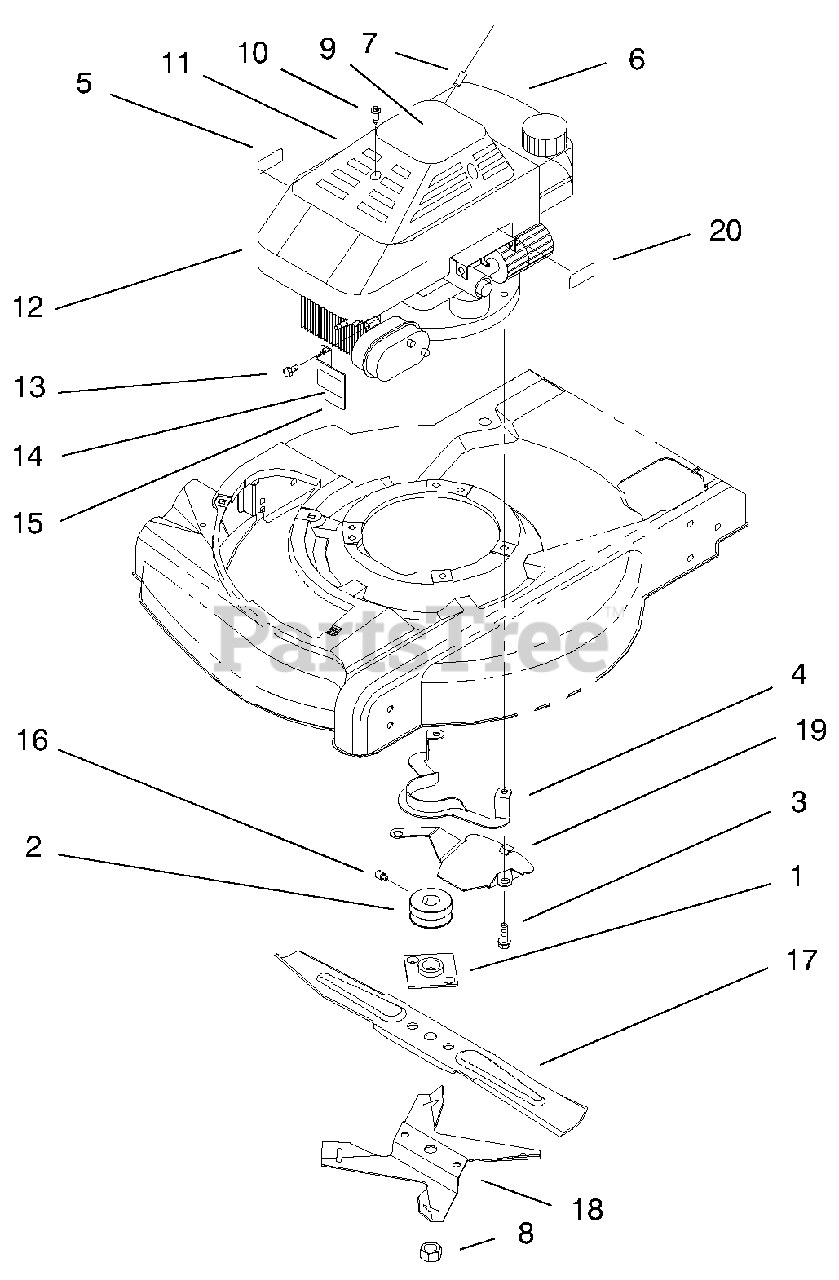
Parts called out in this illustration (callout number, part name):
1	ASM-Plate & Collar
2	Pulley-Engine
3	Screw-Engine
4	Guide-Belt
5	Decal-Oil Instruction
6	ASM-Engine
7	Rope-Stop
8	Nut-Blade
9	Decal-Recoil
10	Screw-Recoil Cover
11	Cover-Starter
12	Shroud-Engine
13	Screw-HSH
14	Decal-Warning
15	Guard-Muffler
16	Screw-Set
17	Blade-21" Whirl
18	Fan-Mulching
19	Shield-Grass
20	Decal-Primer
